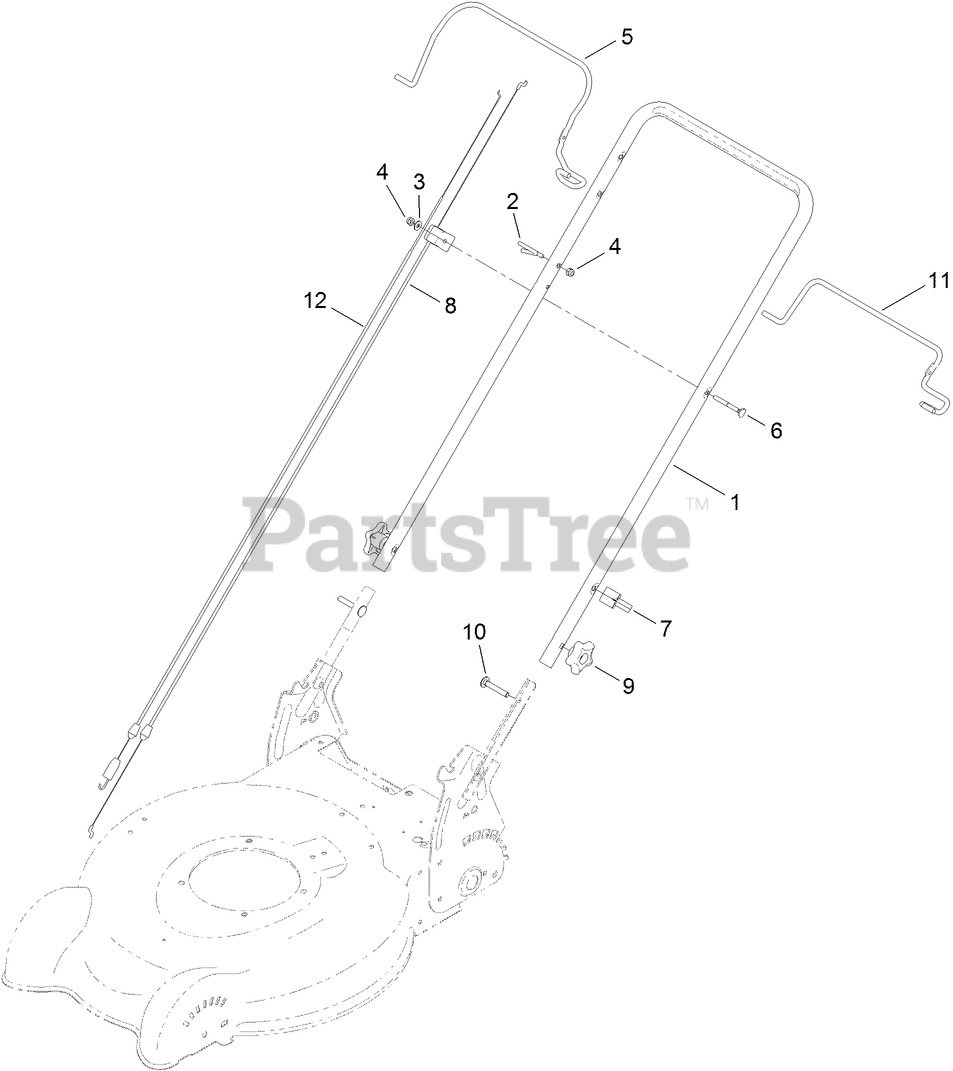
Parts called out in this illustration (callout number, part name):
1	HANDLE-UPPER
2	GUIDE-ROPE
3	WASHER-FLAT
4	NUT-LOCK, NI
6	SCREW-HANDLE
7	GUIDE-CABLE
8	CABLE-BRAKE
9	KNOB-HANDLE
10	BOLT-CARR
11	BAIL-TRACTION, 2-BAIL FLAT
12	CABLE-TRACTION
